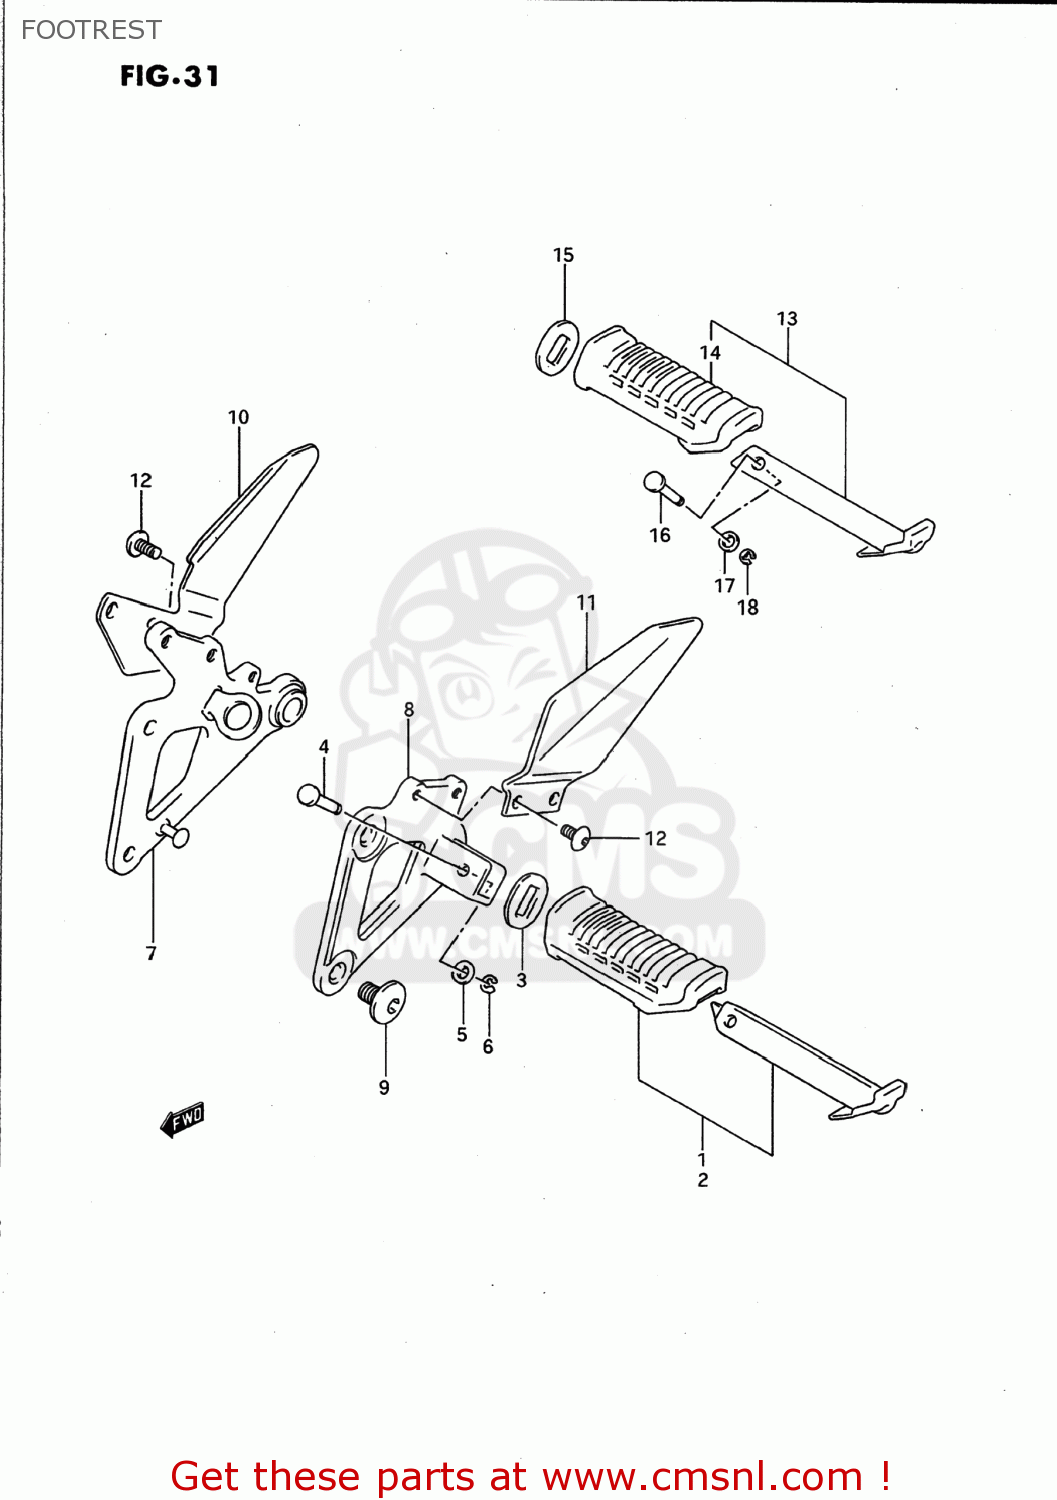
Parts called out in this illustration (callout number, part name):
1	RUBBER,FR FOOTREST,R
2	RUBBER,FR FOOTREST,L
3	WASHER,FOOTREST RUBBER
4	PIN
5	WASHER
6	E-RING
7	BRACKET COMP,FRONT FOOTREST
8	BRACKET,FR FOOTREST,L
9	BOLT(8X25)
10	GUARD,FRONT FOOTREST,RIGHT
11	GUARD,FRONT FOOTREST,LEFT
12	SCREW
13	FOOTREST ASSY,PILLION,R
14	RUBBER,FOOTREST
15	WASHER,FOOTREST RUBBER
16	PIN
17	WASHER
18	E-RING
